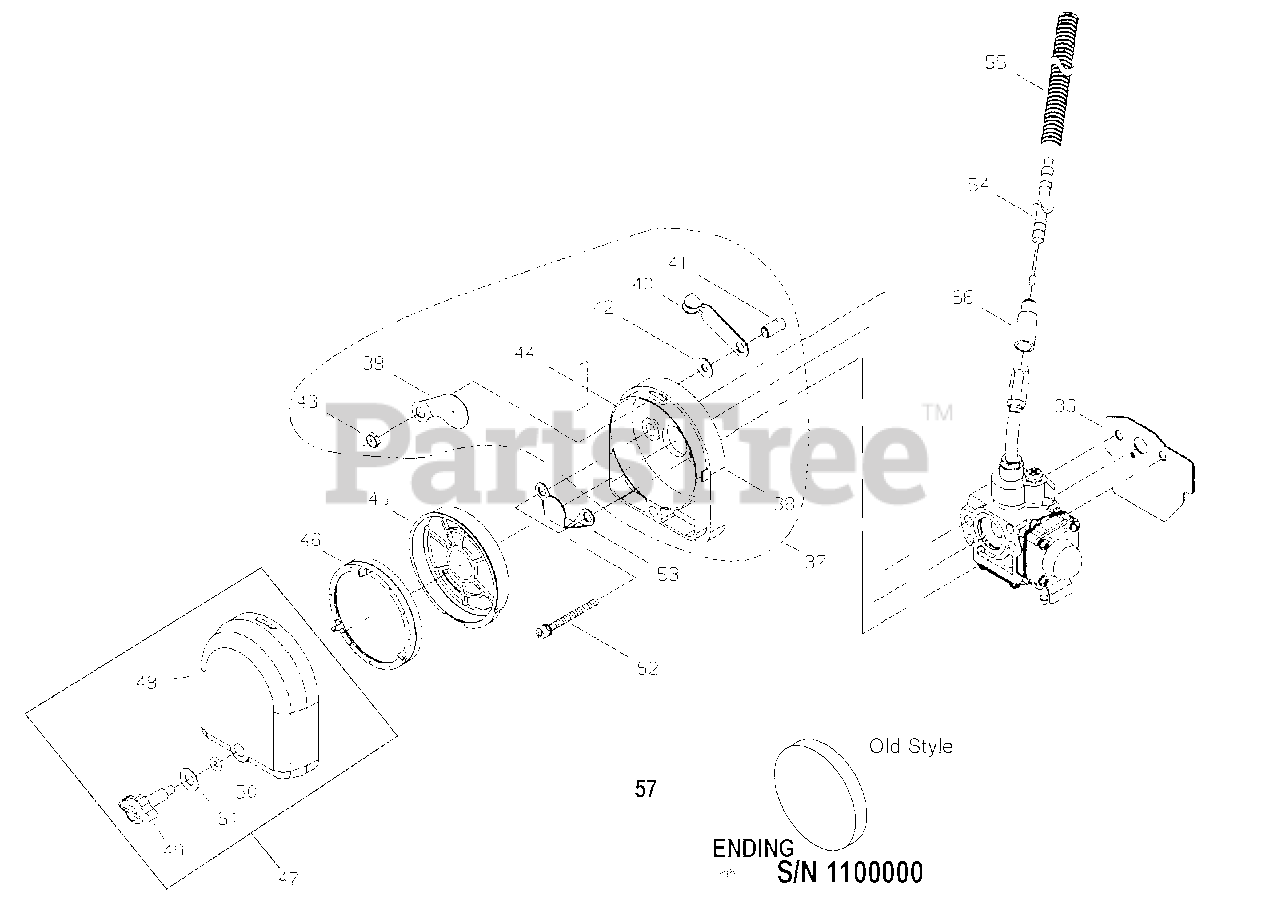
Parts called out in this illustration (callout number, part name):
6	GASKET, INTAKE
37	AIR FILTER CASE ASSY
38	CASE, AIR FILTER
39	PLATE, CHOKE
40	LEVER, CHOKE
41	SHAFT, CHOKE
42	WASHER - CONICAL
43	NUT - 6
44	LABEL - CHOKE
45	BRACKET, FILTER -- REAR
46	FILTER, AIR - HEAVY DUTY
47	AIR FILTER COVER ASSY
48	COVER, AIR FILTER
49	THUMBSCREW
50	O-RING
51	WASHER - CONICAL
52	SCREW - 5X50
53	BRACKET
54	CABLE, THROTTLE
55	TUBE
56	CAP, DUST
57	FILTER, AIR - FOAM
